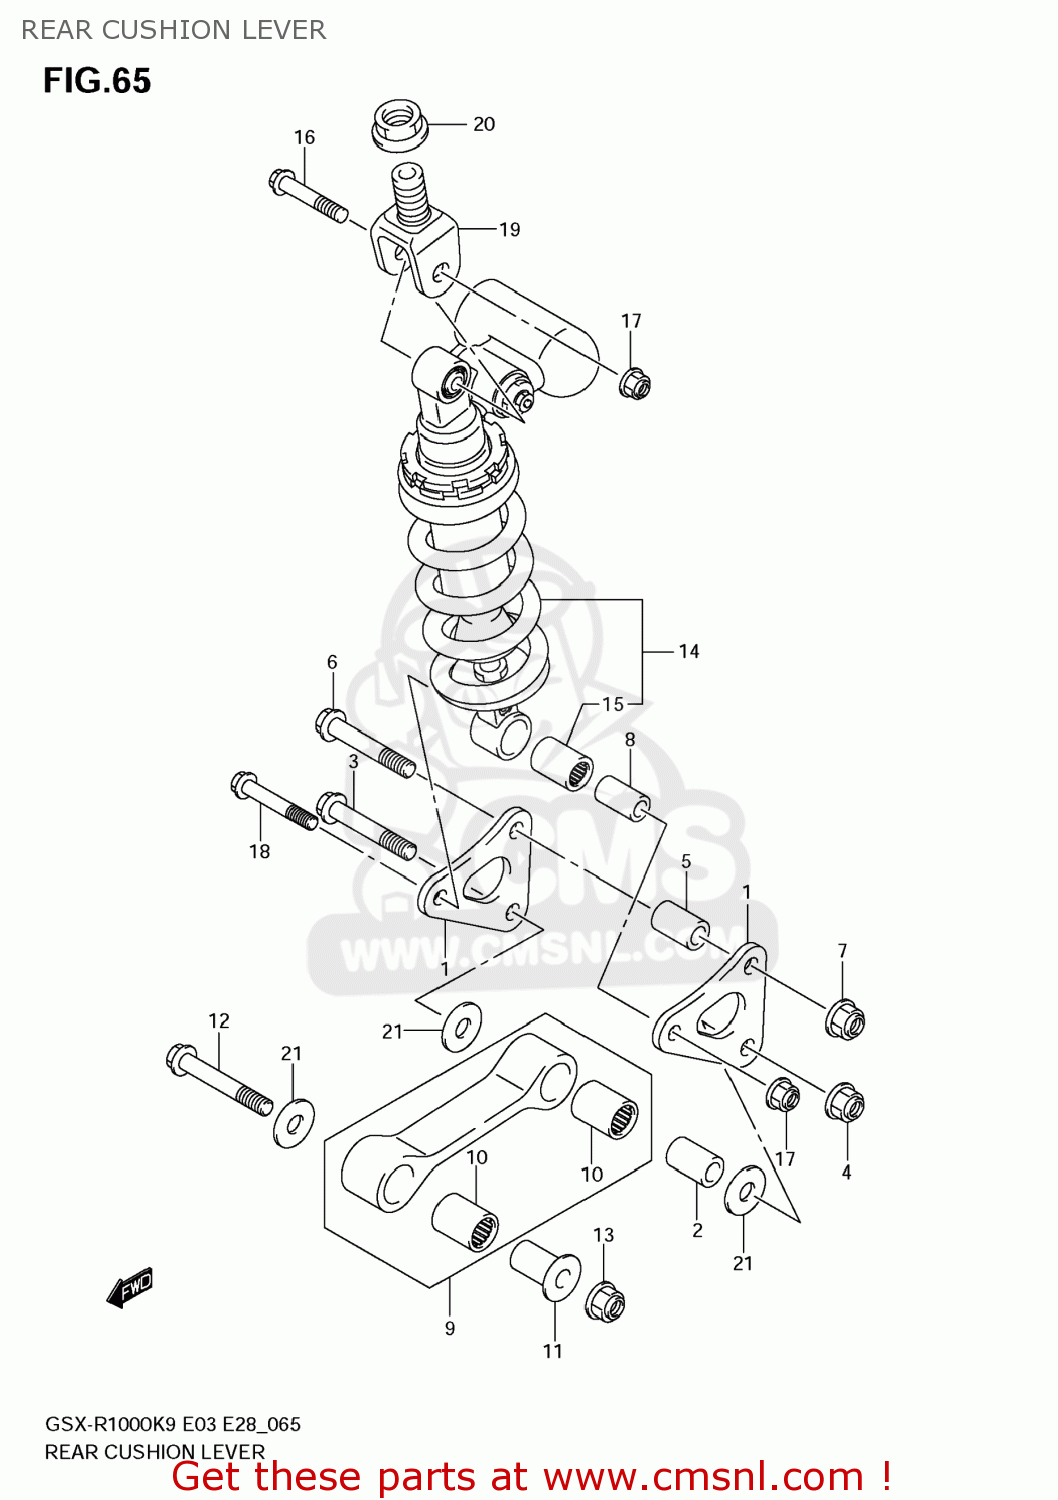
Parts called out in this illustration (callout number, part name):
1	LEVER,RR CUSHION
2	SPACER,RR CUSHION LEVER FR
3	BOLT,RR CUSHION LEVER
4	NUT
5	SPACER,RR CUSHION LEVER FR
6	BOLT,RR CUSHION LEVER
7	NUT
8	SPACER,RR SHOCK ABS LWR
9	ROD SET,RR CUSHION LEVER
10	BEARING(20X27X32)
11	SPACER,RR CUSHION ROD FR
12	BOLT,RR CUSHION ROD
13	NUT
14	ABSORBER SET,RR SHOCK
15	BEARING(17X24X32)
16	BOLT(10X55)
17	NUT
18	BOLT,RR SHOCK ABSORBER LWR
19	BRACKET,RR SHOCK ABSORBER UPR
20	NUT,RR SHOCK ABS BRACKET
21	WASHER(12X34X1)
